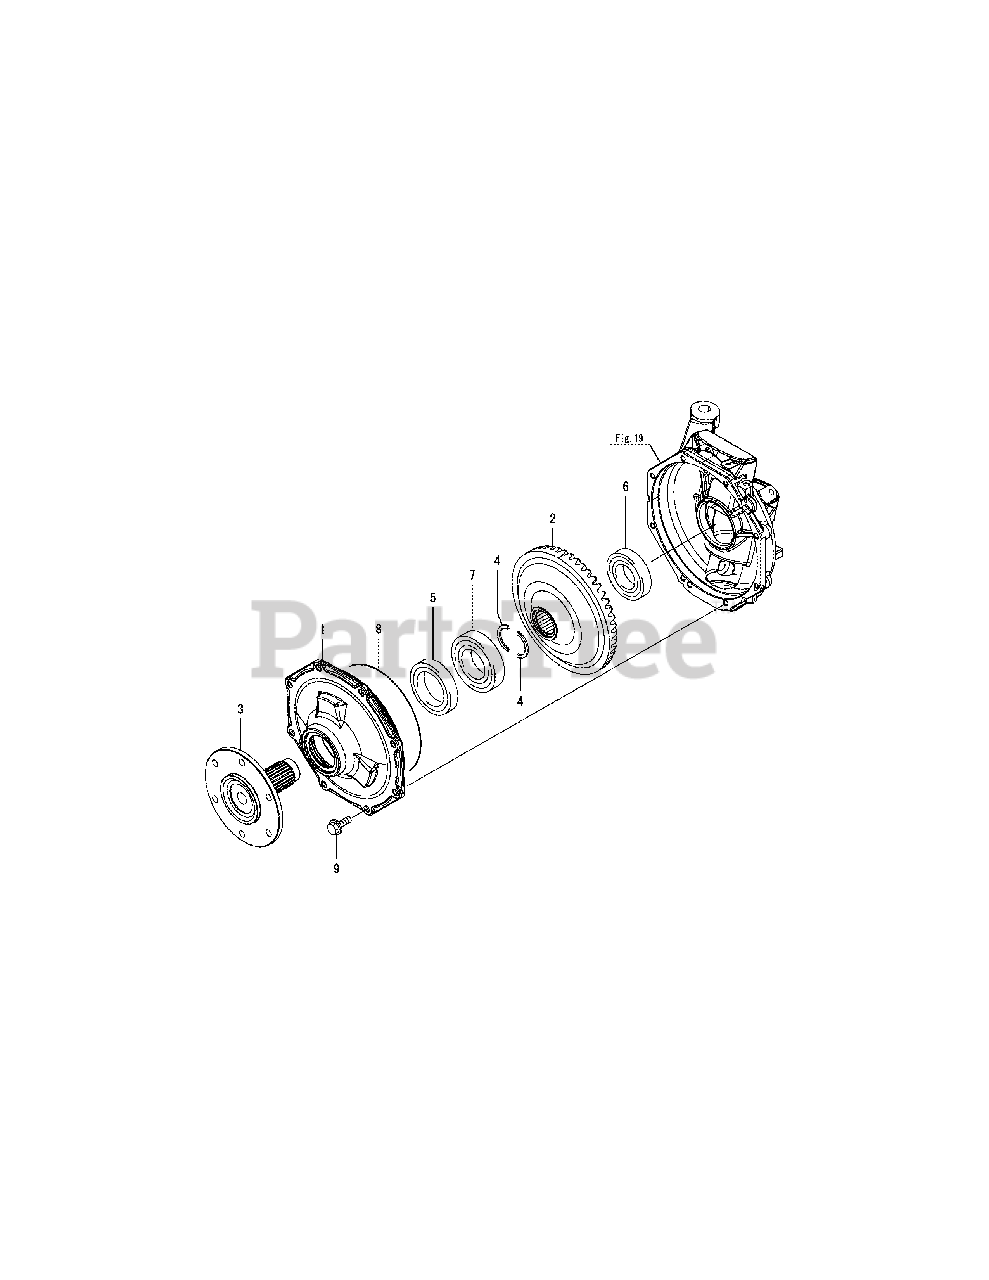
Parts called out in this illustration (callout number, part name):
1	CASE, FRONT BEARING
2	GEAR, FINAL 49
3	SPINDLE, FRONT
4	RING, HALF TIMBER
5	SEAL QLNY527514.5
8	O-RING, 1A G230.0
9	BOLT M10X 30 PLATED
